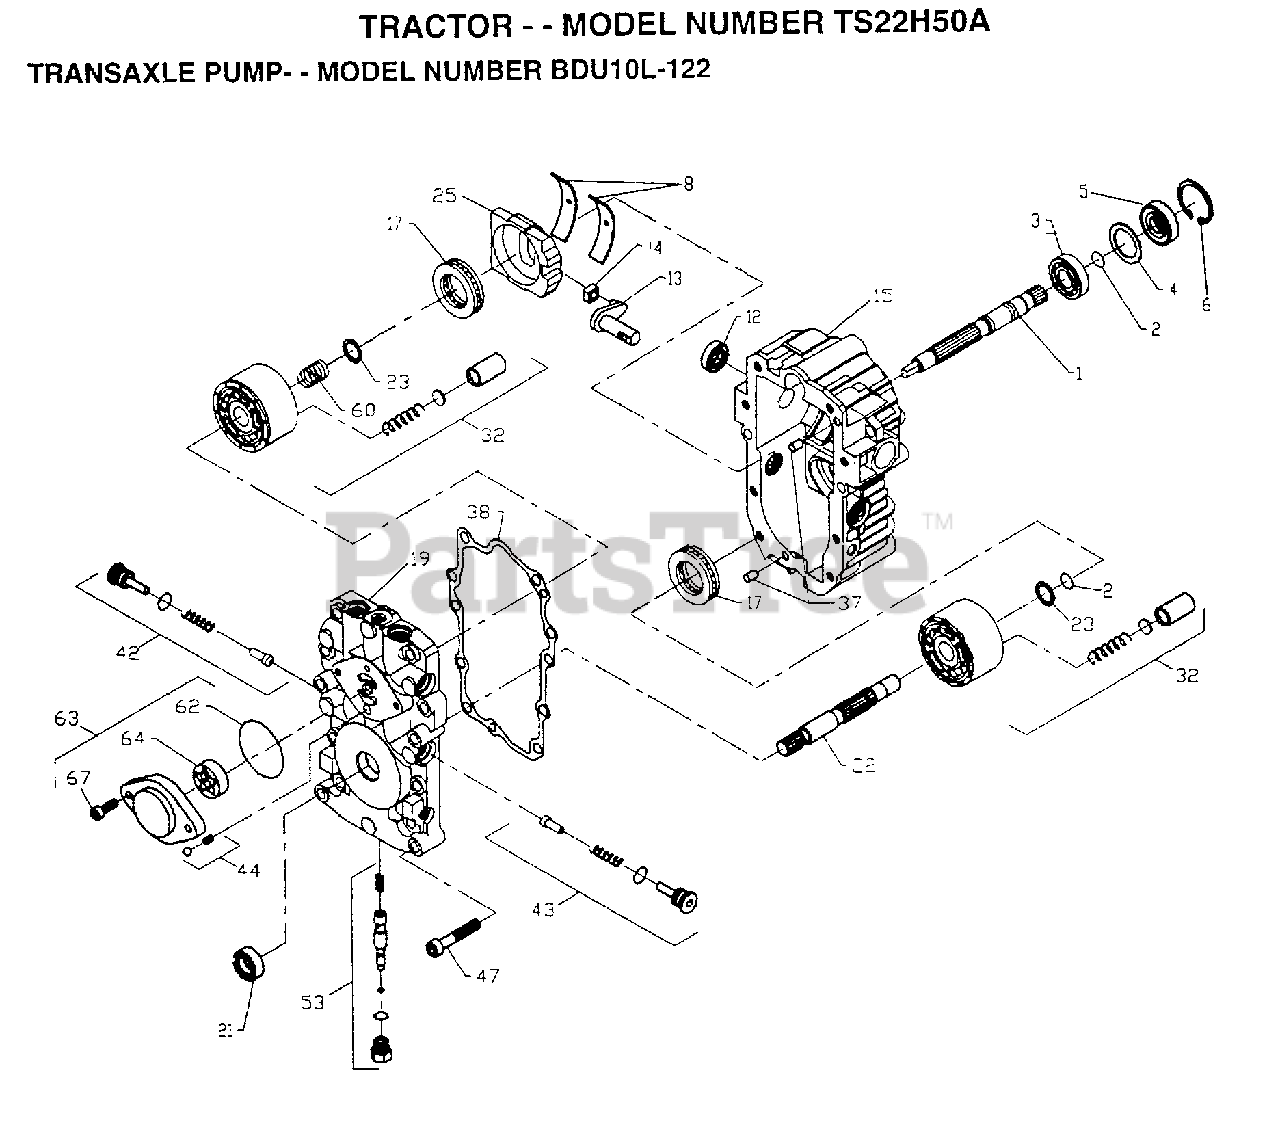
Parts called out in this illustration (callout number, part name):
1	SHAFT.PUMP.50158
2	RETAINIANG RING-(2003016)
3	BALL BEARING
4	SPACER
5	SEAL LIP
6	RING.RET.2003052
8	CRADLE BEARING (2003023)
12	SEAL.9008000-0126
13	TRUNION ARM (2003005)
14	GUIDE.2000015.HYD
15	KIT.HSG.2513035.
19	KIT.CENTER.50642
21	LIP SEAL-9008000-0127
22	SHAFT.MOT.2003034
23	WASHER.2003017
25	"SWASHPLATE,VARIAB"
32	BLOCK.CLYN.70079.
37	PIN
38	GASKET.20030600
42	KIT.VALVE.2510050
43	KIT.VALVE.2510050
44	KIT.RELI.2510011.
47	SCREW9007314-0808
53	"KIT,BYPASS VALVE"
60	SPRING.2003014.
62	0RING.90041011340
63	KIT.CHARG.2513027
64	GEROTOR.J1041008
67	SCREW.CAP.50095.
